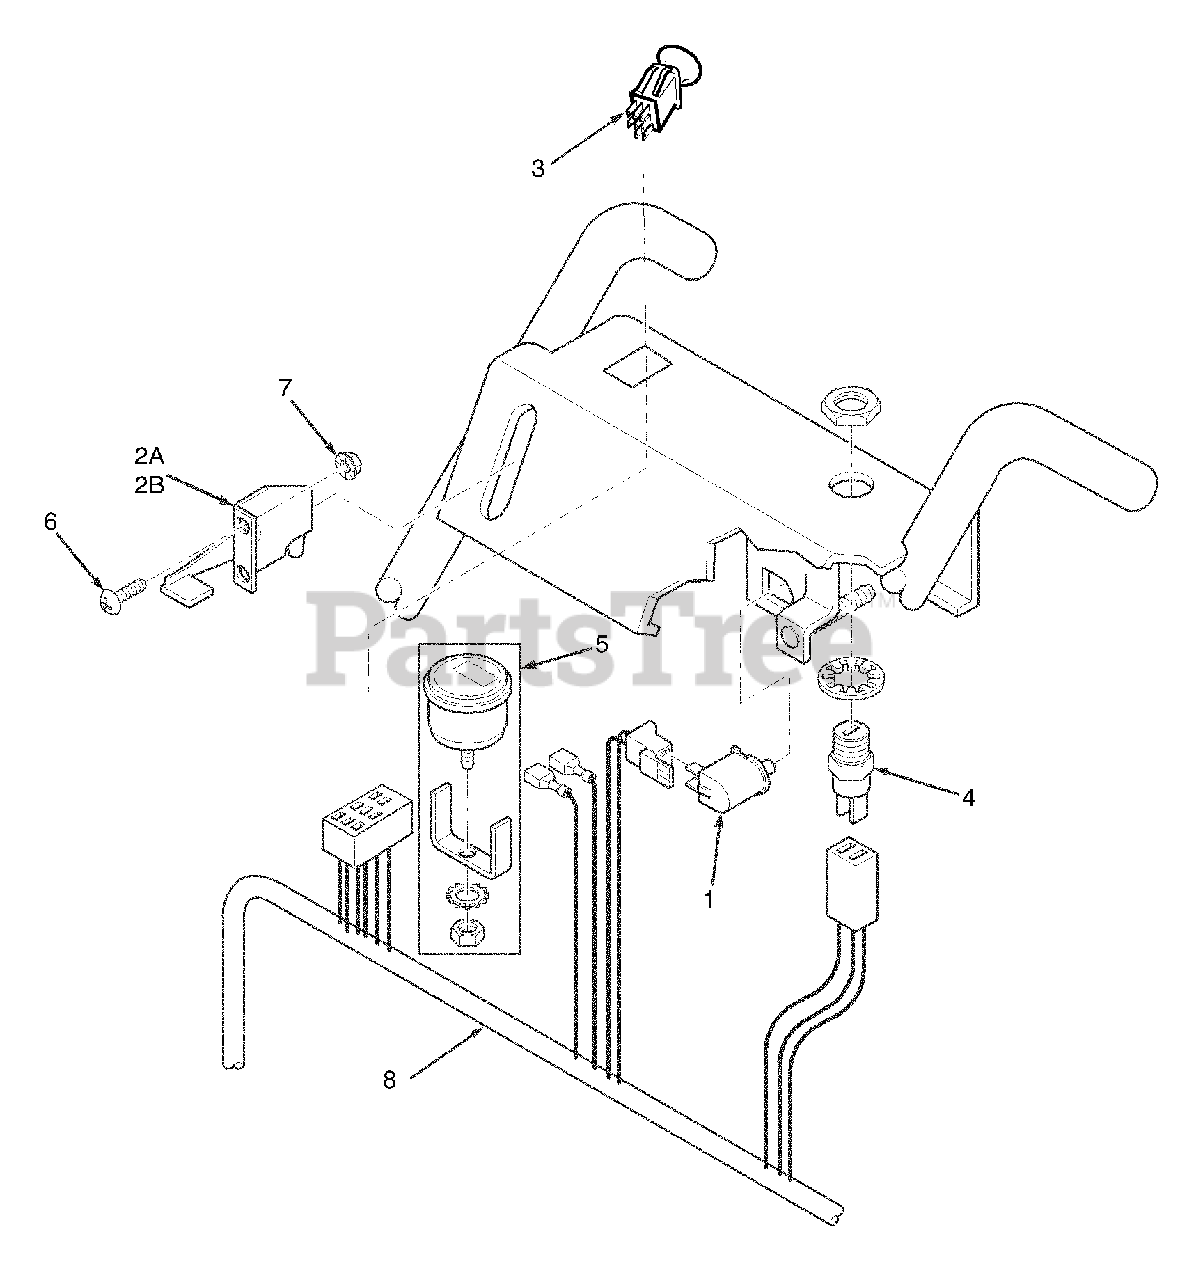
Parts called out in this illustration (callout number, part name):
1	Switch, Neutral Interlock
2B	Throttle Control (15KA & 17KA)
3	Engagement Switch, Electric Clutch
4	Key Switch
5	Hour Meter
6	Screw, #10-32 x .50 Phillips Washer Head
7	Nut, #10-32 Serrated Flange Hex Head
8	Handle Wire Harness, Manual Start
NS	Clamp, Wire Harness
